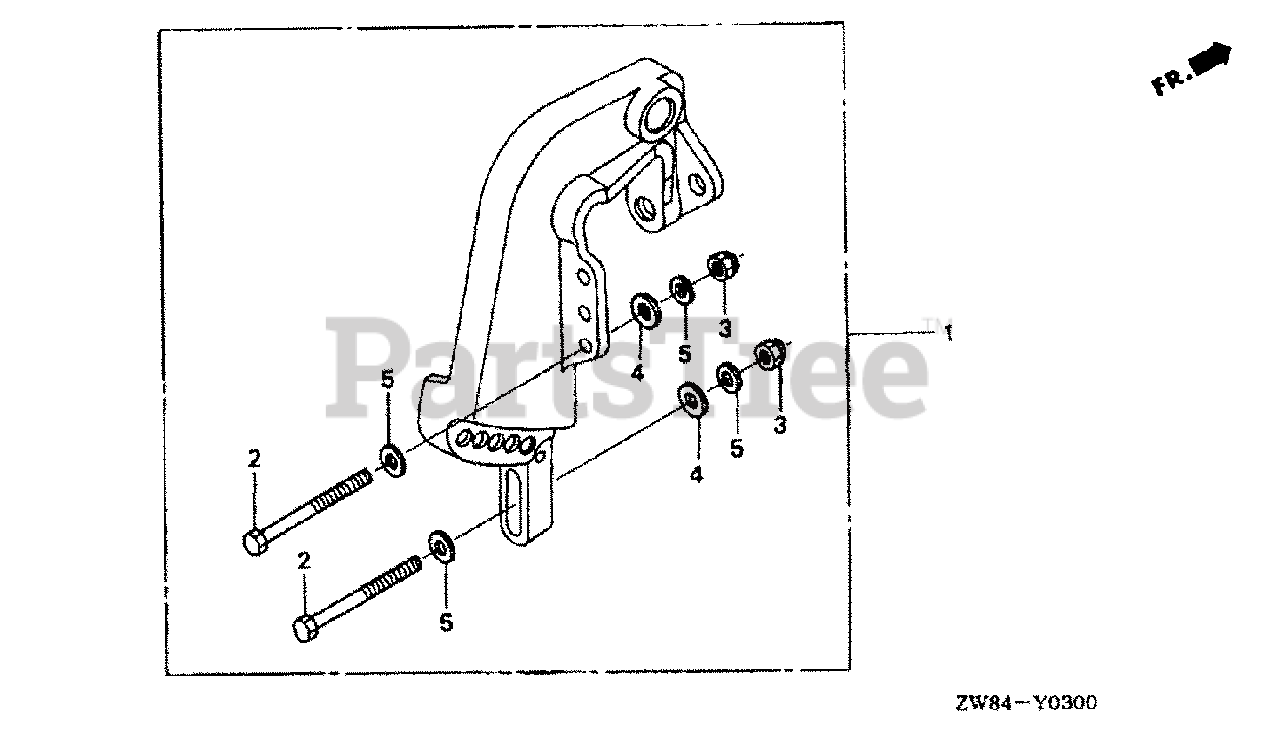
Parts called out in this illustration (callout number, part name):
1	INSTALLATION KIT
2	BOLT, HEX. (10X100)
3	NUT, SELF-LOCK (10MM)
4	WASHER, PLAIN (10MM)
5	WASHER, PLAIN (10MM)
